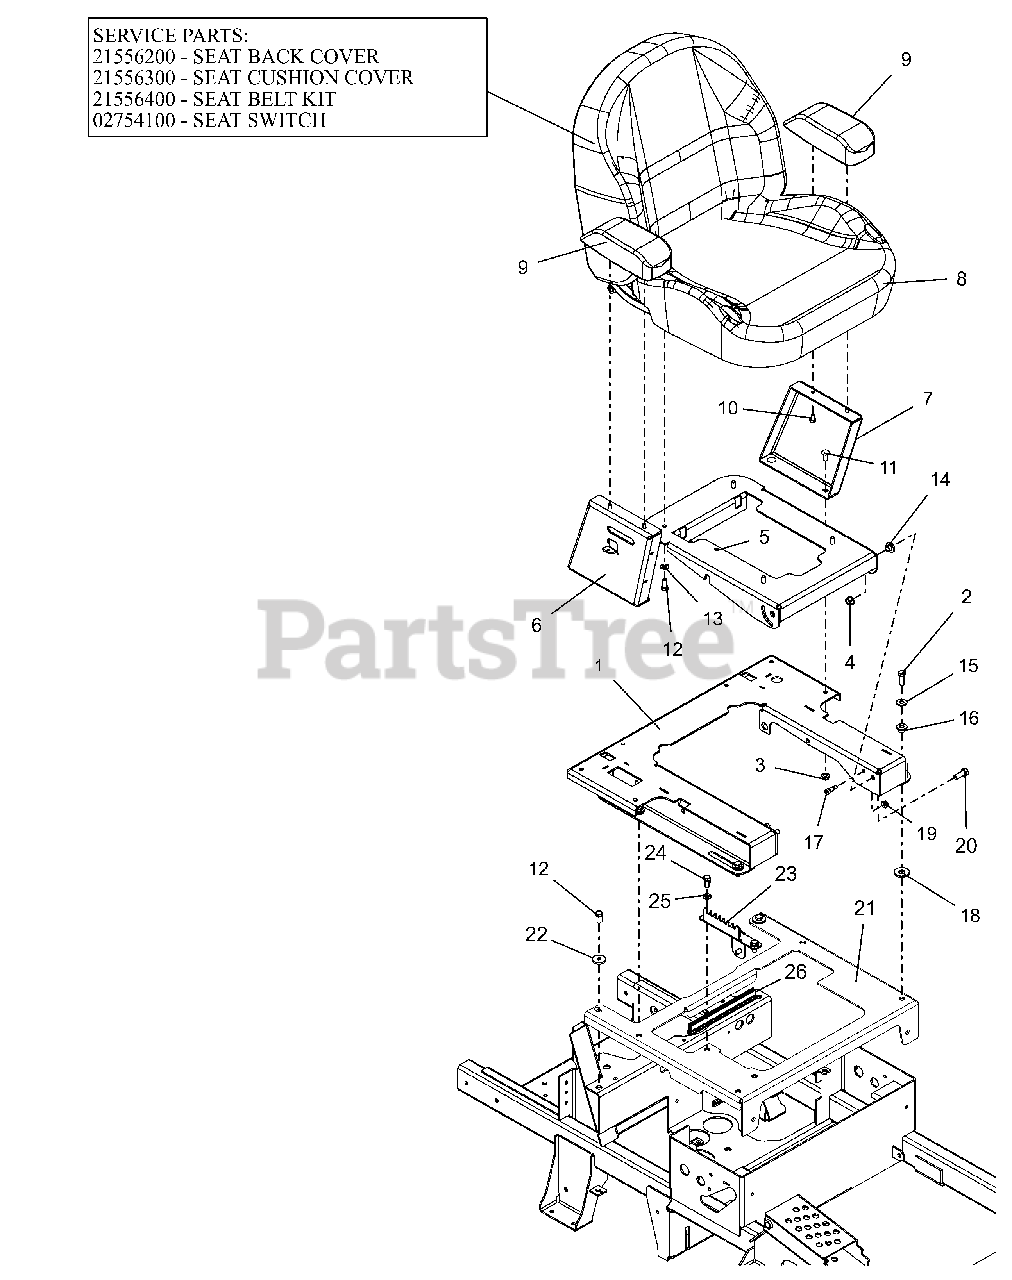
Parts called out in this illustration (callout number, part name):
1	WLDMT, SEAT MOUNTING
2	BLT,HEX .31-18X1.00 G5 ZCC
3	NUT,LK-CTR-FLG .31-18 GF ZCC
4	NUT-LK-CTR-FLG .375-16 GF ZCC
5	WLDMT, SEAT PLATE
6	SUPPORT, RH ARMREST
7	SUPPORT, LH ARMREST
8	SEAT, NON-SUSPENTION
8	COVER, SEAT BACK
8	COVER, SEAT CUSHION
8	KIT, SEAT BELT
8	SWITCH- SNAP MTG N.O.
9	PAD, ARMREST
10	BLT,HEX .25-20X.50 G5 ZCC
11	BLT, RHSSN.31-18X.750 G5 ZCC
12	BLT,HEX .31-18X.75 G5 ZCC
13	WSHR,FLT .344X.688X.065 ZCC
14	BSHG-FLG .385X.500X.875X.406
15	WSHR,FLT .375X.875X.083 ZCC
16	BSHG-FLG, .325X.500X.443X.875
17	BLT-SHLDR .313X.500X.250-20
18	WSHR-FL-DELRIN .505X1.250X.125
19	NUT-LK-CTR-FLG .25-20 ZC120
20	BLT, HEX .38-16X1.00 G5 CKF
21	WLDMT, SEAT MTG PLATE
22	WSHR, FLT .340X1.125X.135 ZCC
23	BRKT, COMPACT PRO SEAT ADJUST
24	BLT,HEX .31-18X.75 G5 ZCC
25	WSHR,FLT .344X.688X.065 ZCC
26	HOLDDOWN, FUEL TANK
